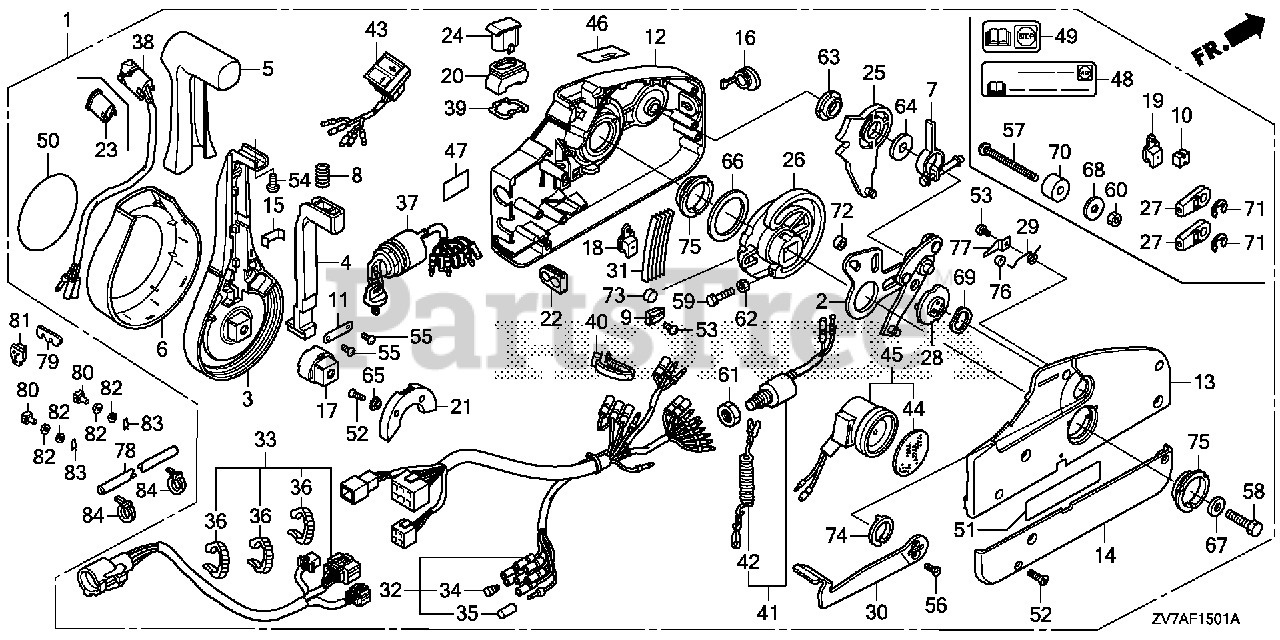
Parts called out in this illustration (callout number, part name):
1	S/R SW 2 LIGH MAN TL
2	PLATE ASSY.
3	LEVER, HAND
4	ARM, NEUTRAL LOCK
5	GRIP
6	COVER, LEVER
7	ARM ASSY., BRAKE
8	SPRING (2)
9	CLIP, DETENT
10	SPACER (1) (LOOSE PARTS)
11	BRACKET
12	HOUSING, FR.
13	HOUSING, RR.
14	PANEL, BACK
16	CAP, RUBBER
17	ADJUSTER
20	SEAL, RUBBER
21	HOLDER, NEUTRAL LOCK
22	GROMMET, WIRE (14)
23	COVER, GRIP
24	CAP, TROLLING CONTROL SWITCH BLANK
25	GEAR ASSY., SHIFT
26	GEAR, DRIVE
27	TERMINAL, CABLE (LOOSE PARTS)
28	DRUM ASSY., FREE THROTTLE
29	SPRING (1)
30	LEVER, FREE THROTTLE
31	SPRING, DETENT
32	CABLE ASSY., REMOTE CONTROL (B)
33	CABLE ASSY., SWITCH PANEL
34	PLUG, CONNECTOR (INNER)
35	PLUG, CONNECTOR (OUTER)
36	TIE, CABLE (2.4X92) (NATURAL)
37	SWITCH ASSY., COMBINATION
39	PLATE, SWITCH
40	BAND, WIRE
41	SWITCH ASSY., EMERGENCY STOP
42	WIRE, EMERGENCY
43	LAMP ASSY., INDICATION (2-LED)
44	PLATE, TURN SIGNAL BUZZER
45	BUZZER, WARNING
46	MARK, FAST IDLE
47	MARK, EMERGENCY STOP (US)
48	MARK, EMERGENCY STOP (US) (LOOSE PARTS)
50	MARK, EMBLEM
51	LABEL, SIGP
52	SCREW (5X18)
53	SCREW (4X6)
54	SCREW (5X10)
55	SCREW (4X10)
56	SCREW (5X12)
57	SCREW (6X90) (LOOSE PARTS)
58	BOLT (8X50)
59	BOLT (5X25)
60	NUT (6MM) (LOOSE PARTS)
61	NUT, HEX. (16MM)
62	NUT (5MM)
63	BEARING (1)
64	WASHER (3)
65	WASHER (4)
66	WASHER (5)
67	WASHER (8MM)
68	WASHER (7) (LOOSE PARTS)
69	WASHER, WAVE
70	SPACER (2) (LOOSE PARTS)
71	E-RING (6MM) (LOOSE PARTS)
72	ROLLER, DRIVE GEAR CAM
73	ROLLER
74	BEARING (2)
75	BEARING (3)
76	ROLLER, FREE THROTTLE
77	CLIP, ROLLER
78	TUBE, CORRUGATE (28MM)
79	PLATE, REMOTE CONTROL CABLE
80	PIVOT, SHIFT
81	GROMMET, CASE (LOWER) (A)
82	WASHER, PLAIN (6MM)
83	PIN, SPECIAL LOCK (6MM)
84	BAND, SELF-LOCK
